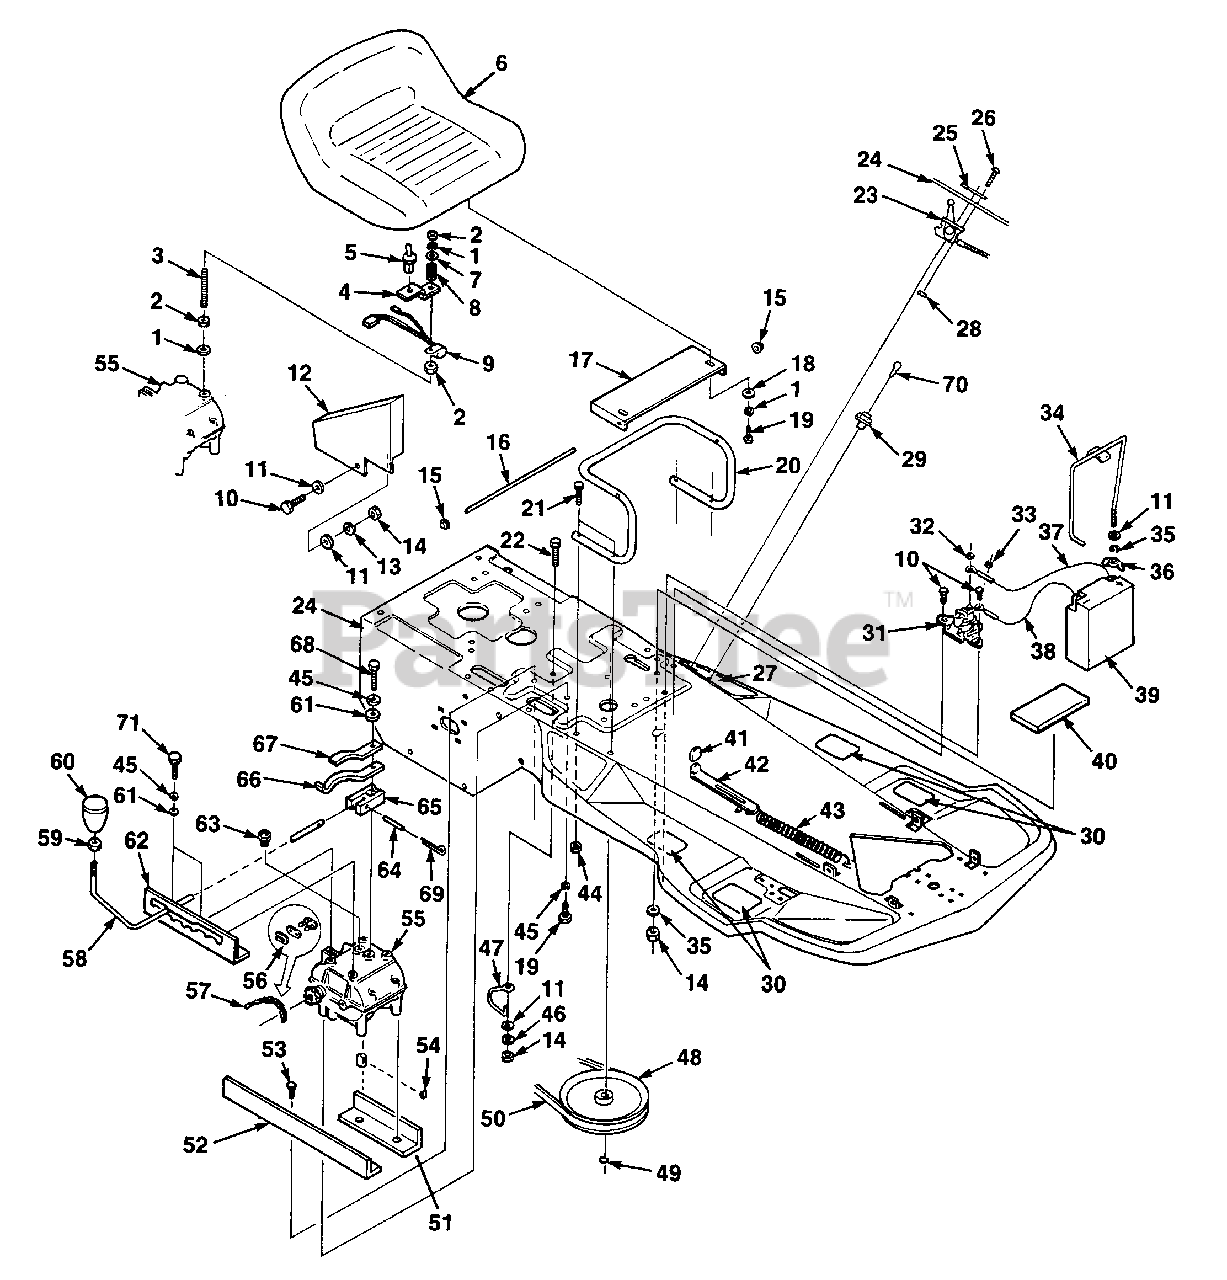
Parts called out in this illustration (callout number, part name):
1	WASHER- Lock 5/16
2	NUT- Hex 5/16-18
3	STUD- 5/16-18
4	BRACKET- Transmission
5	SWITCH- Seat
7	RETAINER- Spring
8	SPRING- Compression
9	MODULE- Safety
10	SCREW- Hex centerlock 1/4-20 x.625
11	WASHER- Plain 1/4"
12	GUARD- Chain
13	WASHER- Lock 1/4-20 x.625
14	NUT- Hex 1/4-20
16	ROD- Seat
17	BRACKET- Seat
18	WASHER- Plain 5/16
19	SCREW- Hex 5/16-18 x.750
20	SUPPORT- Seat
21	SCREW- Hex centerlock 1/4-20 x 1.5
22	SCREW- Hex centerlock 1/4-20 x .825
23	CONTROL- Throttle
25	PLATE- Throttle
26	SCREW- Rd. hd. 10-24 x 1/2
27	DECAL- Throttle
28	NUT- Hex 10-24
29	SWITCH- Ignition
30	PAD- Foot
31	SOLENOID
32	NUT- 1/4-20
33	NUT- Hex 8-32
34	BRACKET- Battery
35	WASHER- Lock 1/4
36	NUT- Wing 1/4-20
37	CABLE- Battery
38	CABLE- Battery ground
39	BATTERY
40	PAD- Battery
41	KNOB- Tab
42	LATCH- Brake
43	SPRING- Extension
44	NUT- Hex centerlock 1/4-20
45	WASHER- Lock 5/16
46	WASHER- Lock 1/4
47	BELT- Guide
48	TRANSMISSION PULLEY
49	RING- Snap
50	BELT- Transmission
51	ANGLE- Short
52	ANGLE- Long
53	SCREW- Hex cap 1/4-20 x 3/4
54	KEY- Woodruff
55	TRANSMISSION
56	LINK- Connecting
57	CHAIN #40
58	LEVER- Gear
59	NUT- Hex jam 3/8-24
60	KNOB- Shift
61	WASHER- Plain 5/16
62	LOCATOR- Gear
63	SWITCH- Neutral safety
64	PIN- Roll
65	BRACKET- Pivot
66	LEAF- Spring
67	LEAF- Spring
68	SCREW- Hex 1/4-20 x.875
69	PIN- Cotter
70	KEY- Ignition
71	SCREW- Taptite
